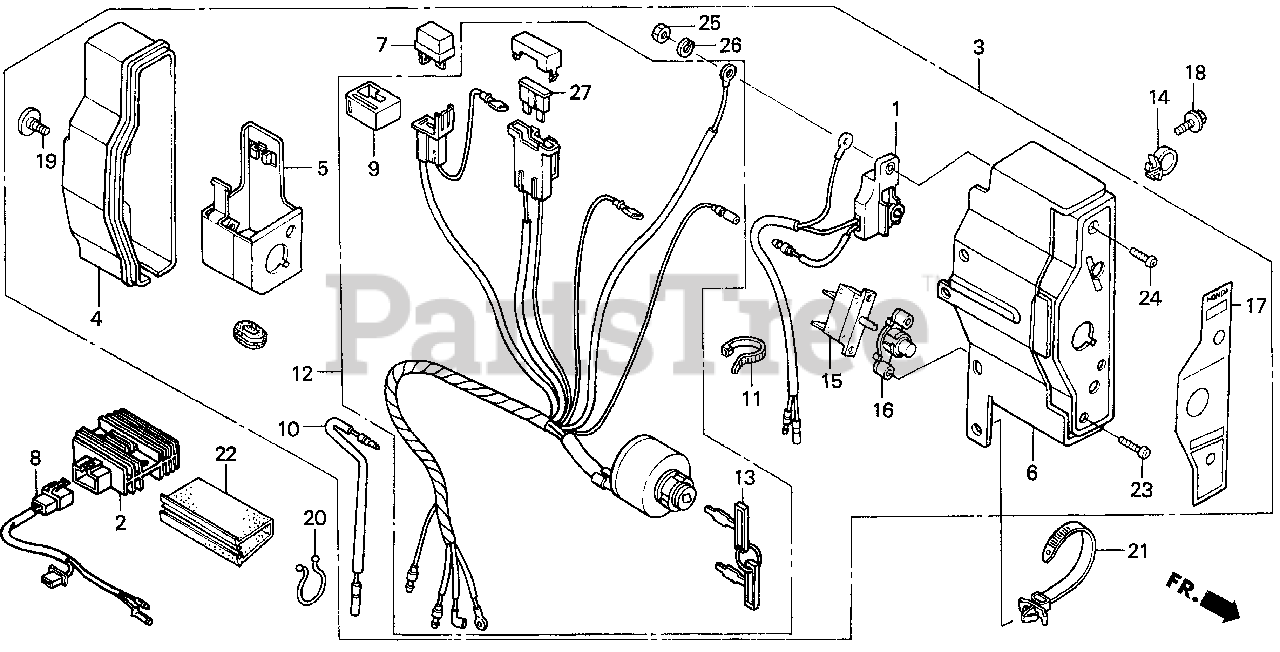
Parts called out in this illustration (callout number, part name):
3	BOX ASSY., CONTROL (EXP-ALERT,3A) *R8*
4	CASE, CONTROL
5	BRACKET, CASE MOUNTING
6	PANEL, CONTROL *R8**R8* (BRIGHT RED)
7	RECTIFIER ASSY., SILICON (STANLEY)
9	SUSPENSION, CONNECTOR
10	SUB-HARNESS
11	BAND
12	SWITCH ASSY., COMBINATION
13	KEY
14	HOLDER, STOP SWITCH WIRE
15	PROTECTOR, CIRCUIT (3.5A)
16	LENS ASSY., PROTECTOR
17	PANEL, CONTROL BOX (EXTERNAL)
18	BOLT, FLANGE (6X12) (CT200)
19	SCREW, SPECIAL (6X12)
20	CLIP, PURSE LOCK
21	STRAP, CABLE (118MM) *NH1L* (BLACK)
22	TUBE, FASTENER (30)
23	SCREW, PAN (3X12)
24	SCREW, PAN (4X12)
25	NUT, HEX. (4MM)
26	WASHER, SPRING (4MM)
27	FUSE, BLADE (15A)
